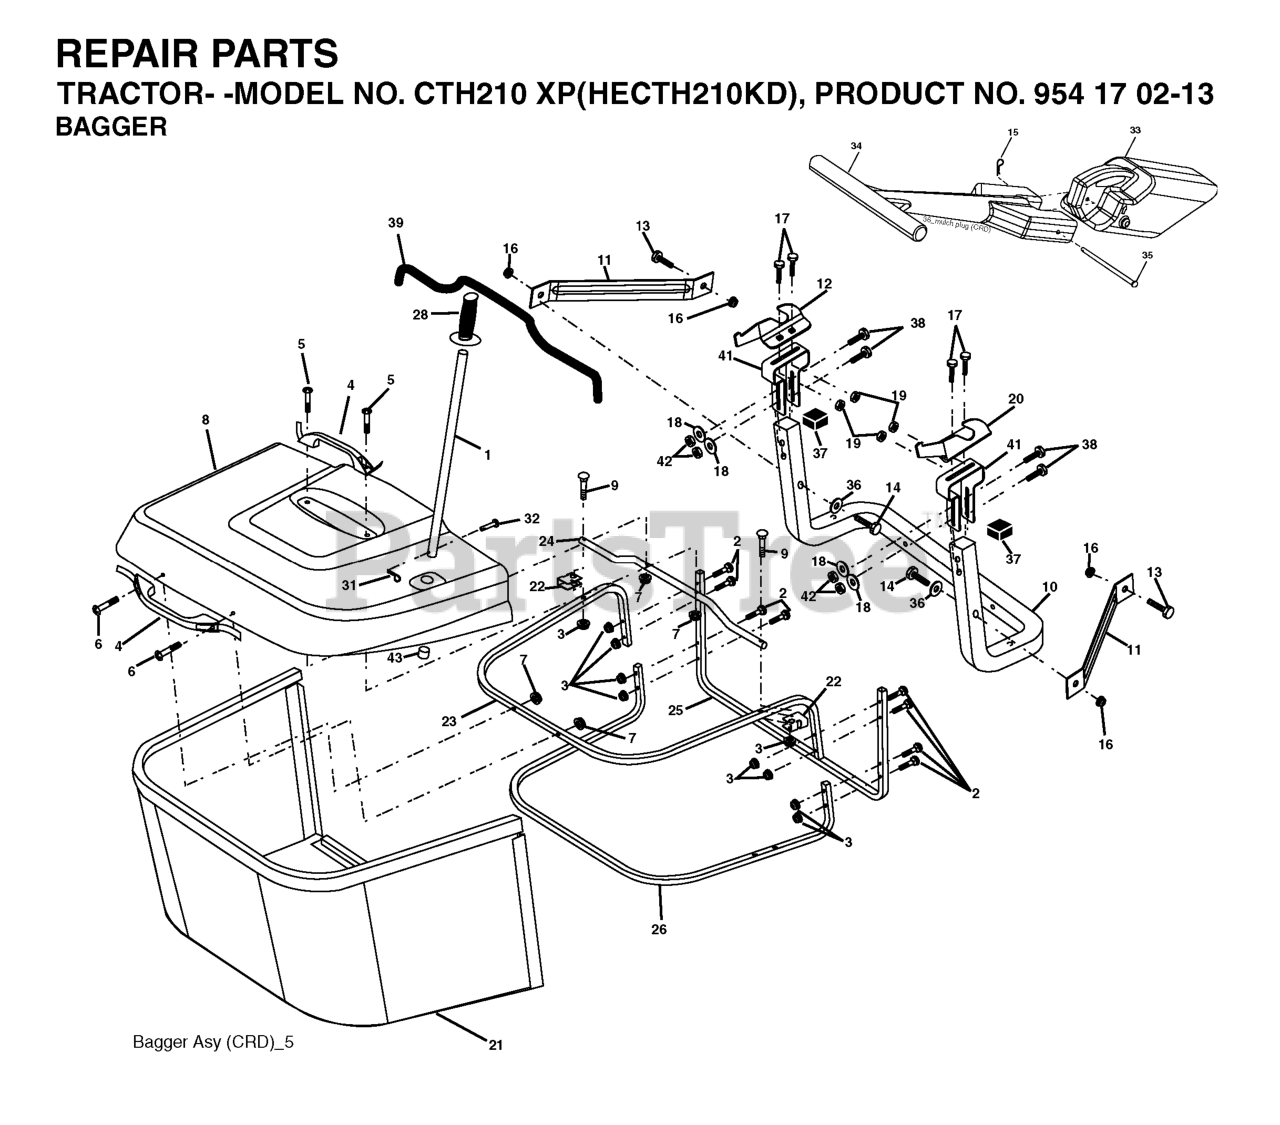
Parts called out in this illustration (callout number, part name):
1	TUBE HANDLE
2	Bolt Carriage 1/4-20 x 2.0 Gr.5
3	NUT T
4	HANDLE.BAGGER.W/LVRS.BLK.CRD
5	SCREW.PAN.HEAD
6	REPL BY 532 75 00-29
8	COVER.PNT.BGR.CRD.WSLOTS.MS668
9	Bolt Carriage 1/4-20 x 2.25d x Gr.5
10	TUBE
11	BRACKET.SUPPORT.UPPER.BAG.CRD
14	BOLT-HEX EAK
15	RETAINER-SPRNG RB
16	NUT LOCK FLG 3/8-16 UNC
17	RP BOLT 5/16-18 X3/4 ZN/YEL GR
18	WASHER M
19	NUT LOCK HEX FLANGE 5/16-18
20	BRACKET
21	GRASS BAG
22	BRKT.SIDE.BAG.CRD
23	TUBE.UPPER.BAG.CRD
24	TUBE.PIVOT.BAG.CRD.BLACK
26	TUBE.LOWER.BAG.CRD
28	GRIP.HANDLE.BLACK
31	RETAINER CLIP
32	RIVET,DRILLED
33	MULCH PLUG, CTH150
34	HANDLE.MULCHER.92.CRD (2 2)
36	WASHER
37	Plug Support Bagger CRD
38	BOLT.5/16-18X2.5
39	SEAL.TRIM.37'
41	BRKT.VERT.ADJ.BAGGER.CRD
42	NUT.71038.31-18.HEX.NYLOCK
43	PLUG, TUBING END
